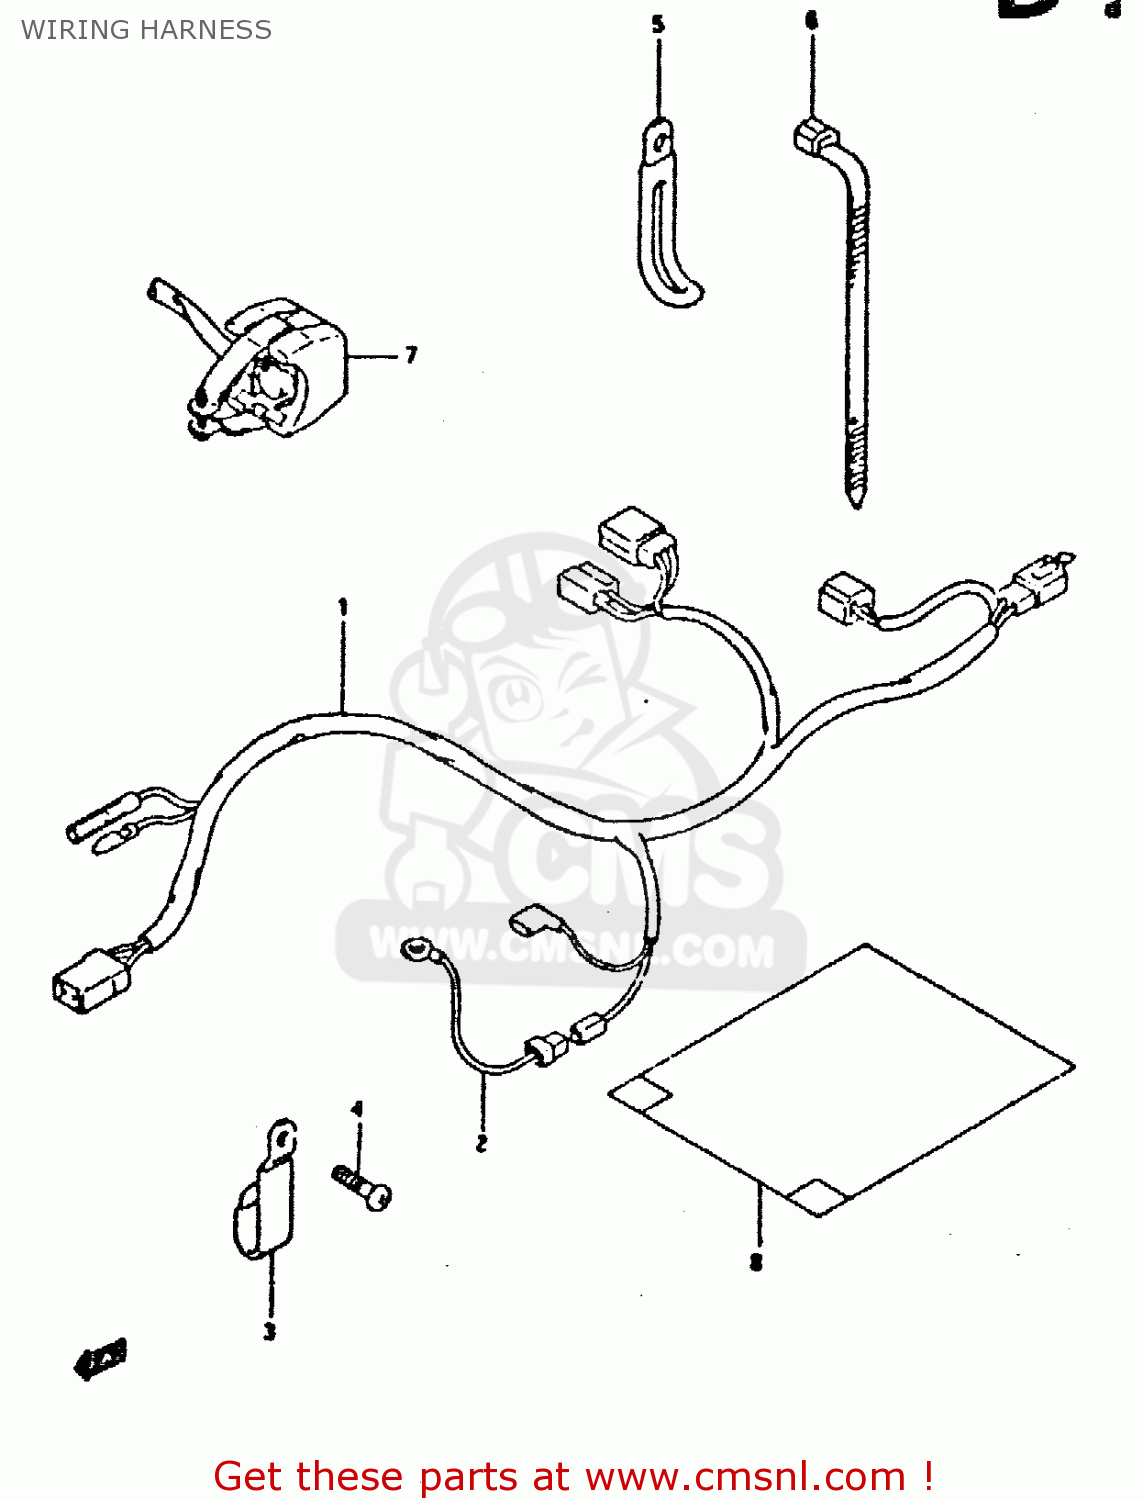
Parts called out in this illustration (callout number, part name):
1	HARNESS,WIRING
2	WIRE
3	CLAMP
4	SCREW
5	CLAMP L:62
6	CLAMP L:165
7	SWITCH ASSY,ENGINE STOP
8	COVER,WIRING HARNESS
